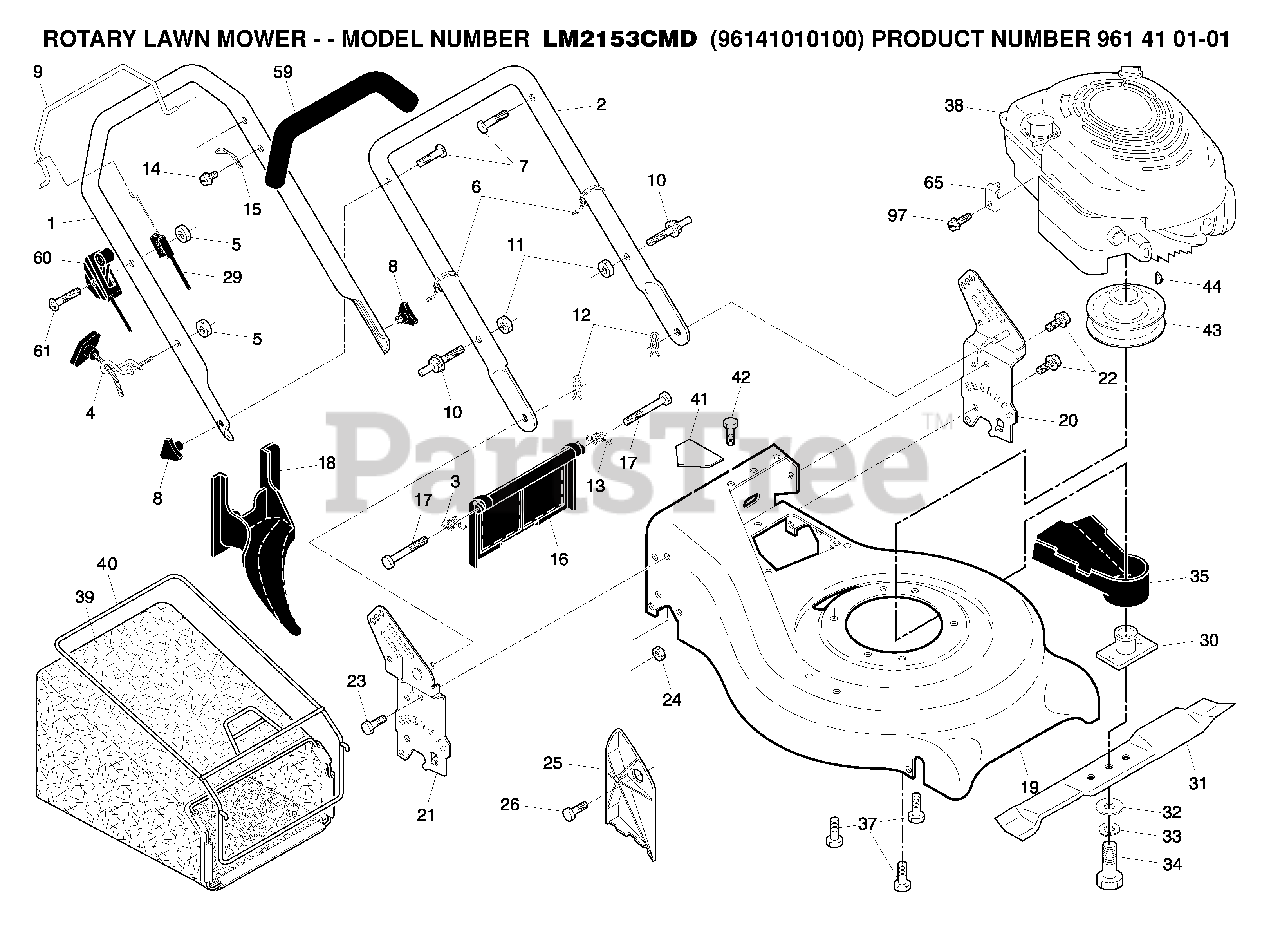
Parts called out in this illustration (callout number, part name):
2	HANDLE LOWER
3	SPRING, REAR DOOR, RH
4	GUIDE.ROPE.STD.BLK.ZIN
5	NUT
6	TIE GUIDE
7	BOLT, HANDLE 5/16-18X1.75
11	NUT.CENTERLOCK.5/16-
12	HAIRPIN COTTER
13	SPRING.LH.REAR.DOOR.21.RWGD
15	BRACKET UPSTOP
16	DOOR.REAR.PLASTIC.21.RWGD.BLAC
18	PLUG.MULCHER.RGD.21.
20	BRKT.ASM HNDL
21	BRKT.ASM.HNDL
22	SELF-TAPPING SCREW 5/16-18X3/4
23	BOLT, HEX HEAD 5/16-18
24	NUT.71038.31-18.HEX.NYLOCK
25	CLIPPING DEFLECTOR
29	ENGINE ZONE CONTROL
30	ADAPTER.BLADE
31	BLADE.21.PUSH
32	WASHER,HARDEN
33	LOCKWASHER
34	SCREW, HEX HD 3/8-24 X 1-3/8
37	BOLT 3/8-16X1-1/8
40	FRAME.CATCHER.21.RGD.AG
41	DECAL.INTERNATIONL.CUTFINGER
43	PULLEY.ENG.25MMM
44	HI-PRO KEY
59	GRIP.HANDLE.FOAM
60	CONTRL.THROTTLE.
65	CABLE CLAMP(ENGINE)
97	SCREW.HEX.HEAD.WASHER.10-16
